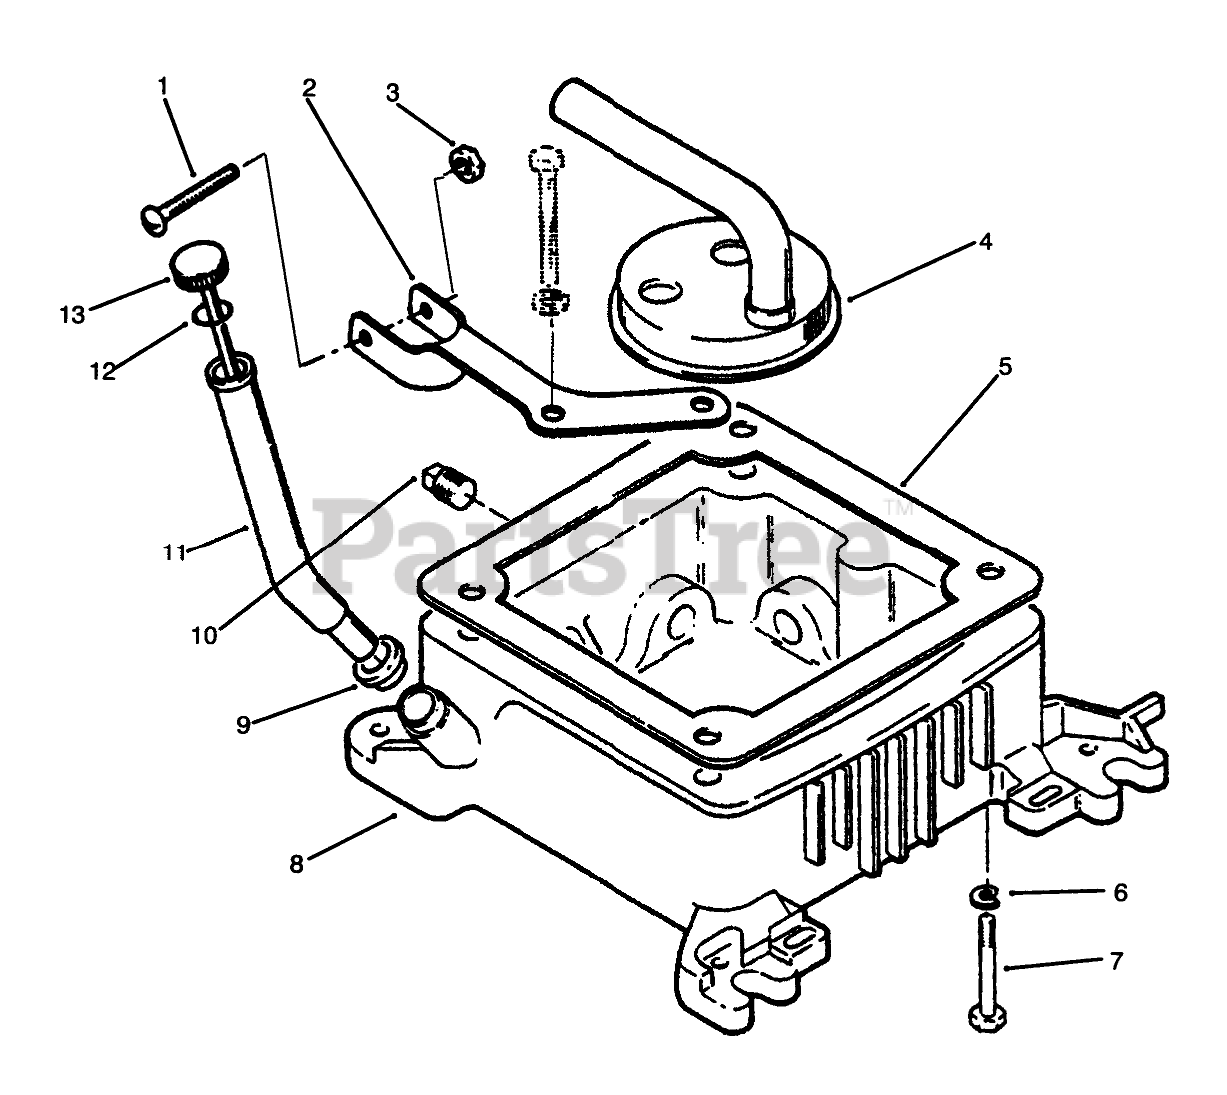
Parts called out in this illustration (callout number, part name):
1	SCREW - PAN HEAD
2	BRACKET-FILL TUBE
3	NUT - SPEED
4	OIL CUP ASM
5	GASKET
6	WASHER-FLAT
7	HHCS 3/8-16 X 3 3/4
8	Base-Oil (Incl. Ref. #10)
9	SEAL-OIL FILL TUBE
10	PLUG - SQUARE HEAD
11	Tube-Oil Fill
12	SEAL 0-RING
13	Cap & Indicator-Oil Fill (Incl. Ref. #12)
